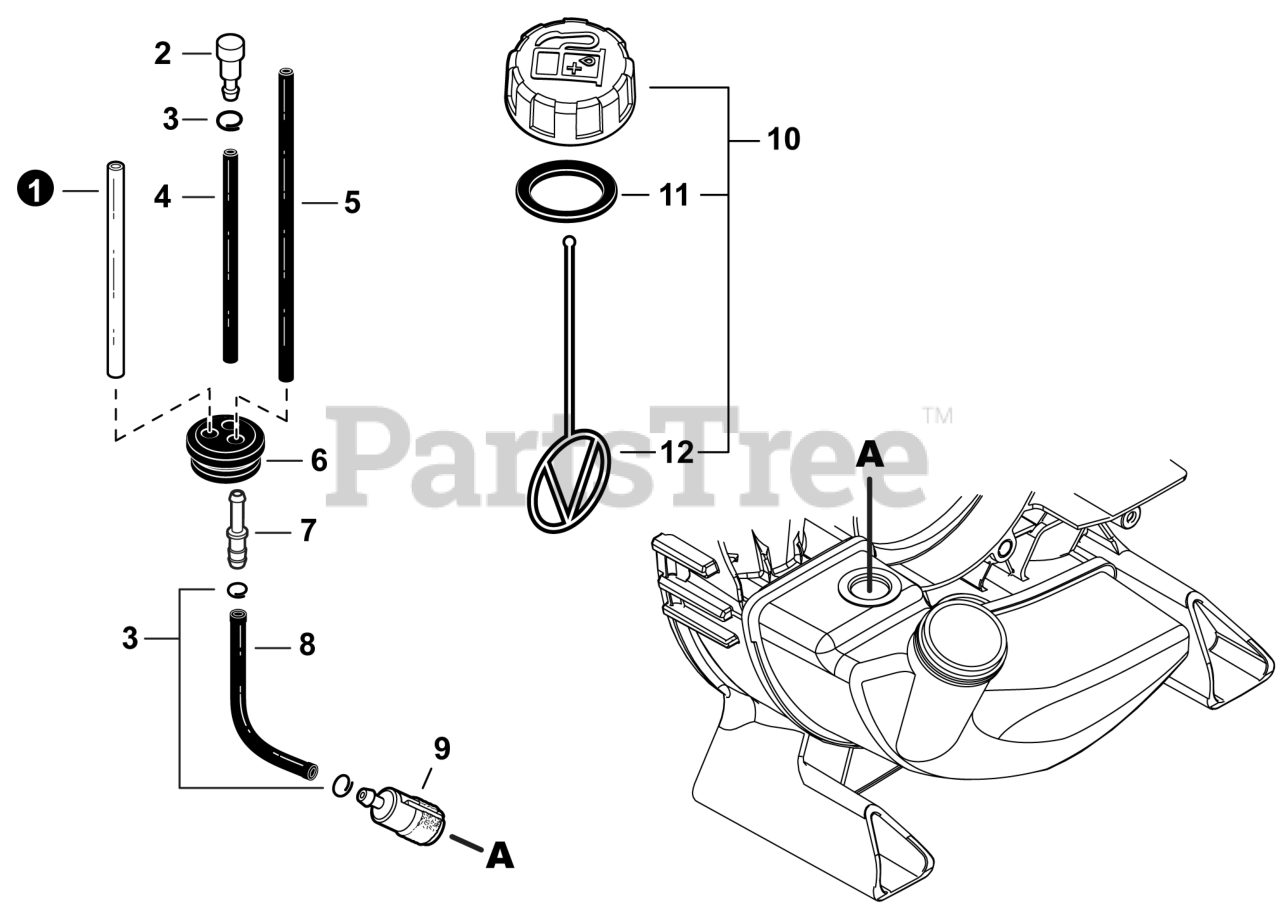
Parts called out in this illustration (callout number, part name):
1	PIPE, FUEL 3x6x85 CLEAR
2	VENT ASSY
4	PIPE, FUEL 3x5x60 BLACK
5	PIPE, FUEL 3x5.5x78 BLACK
6	GROMMET, FUEL 5
7	CONNECTOR, PIPE 5x3.5
8	PIPE, FUEL 3x5x150 BLACK
9	FILTER, FUEL
10	CAP ASSY, FUEL
11	GASKET, FUEL CAP
12	CONNECTOR, CAP L= 100 MM
